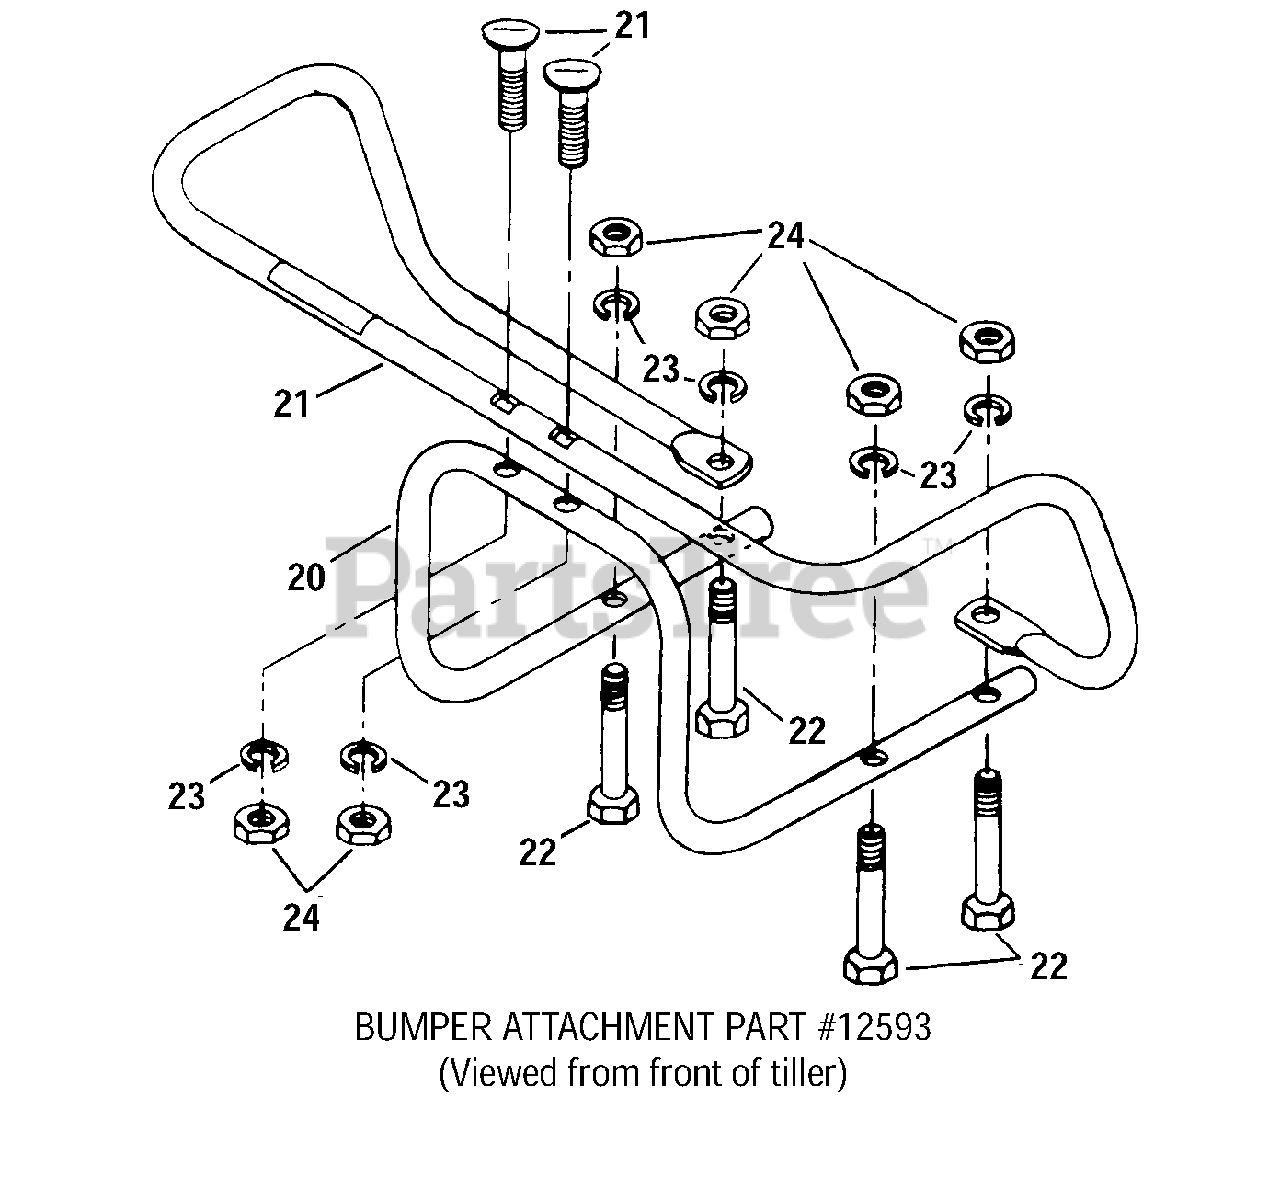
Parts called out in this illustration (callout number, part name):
20	Bumper-bottom section
21	Bolt-curved head, 5/16-18 x 2 (special bolt);
22	Bolt-hex hd., 5/16-18 x 2-1/2, not avail. separately (order #1915811 hardware kit
23	Lockwasher-5/16, not avail. separately (order #1915811 hardware kit
24	Nut-hex, 5/16-18, not avail. separately (order #1915811 hardware kit
12593	Bumper Attachment
